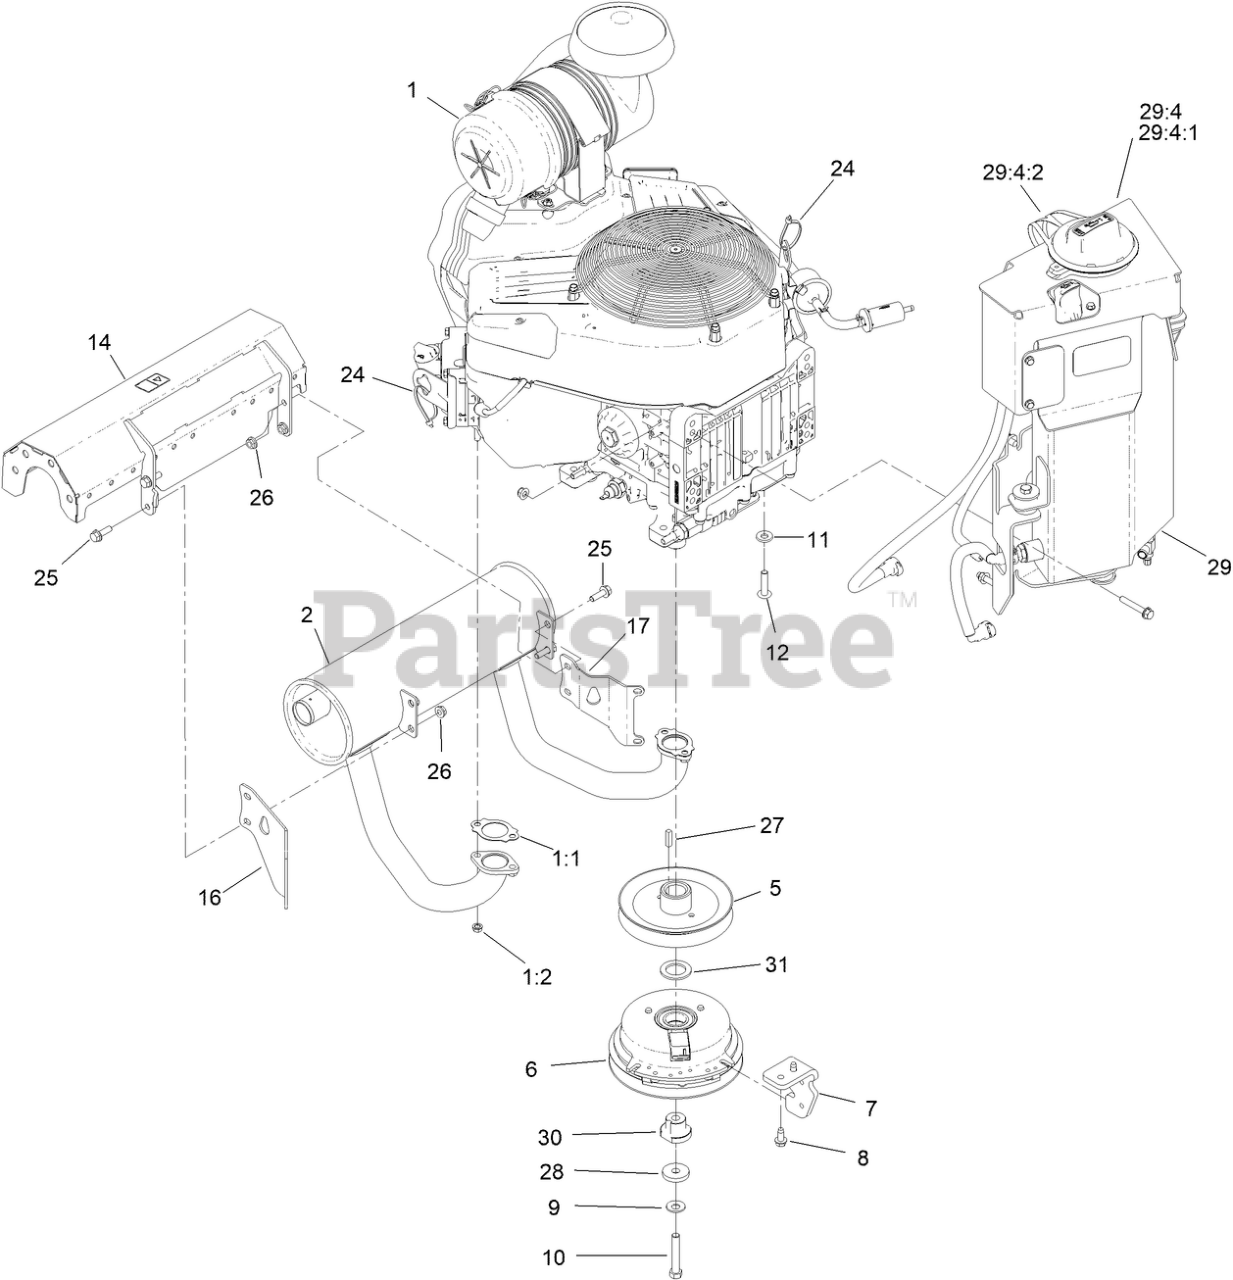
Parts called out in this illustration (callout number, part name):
1	ENGINE VANGUARD EFI
1:1	GASKET-EXHAUST
1:2	NUT-HEX
2	MUFFLER, BASCO 37HP
5	PULLEY
6	CLUTCH-200CMS
7	BRACKET, CLUTCH STOP
8	SCREW-HWHTF
9	WASHER-SPRING
10	SCREW-HH
11	WASHER-BELLEVILLE
12	SCREW-BHTF
14	MUFFLER GUARD ASM
16	BRACKET-MUFFLER
17	BRACKET-MUFFLER
24	TIE-CABLE
25	SCREW-HHF
26	NUT-HF
28	WASHER
29	OIL GUARD ASM
29:4	RESERVOIR-OIL
29:4:1	OIL DIPSTICK ASM
29:4:2	OIL TANK CAP ASM
30	SPACER, D-DRIVE
31	WASHER-THRUST
